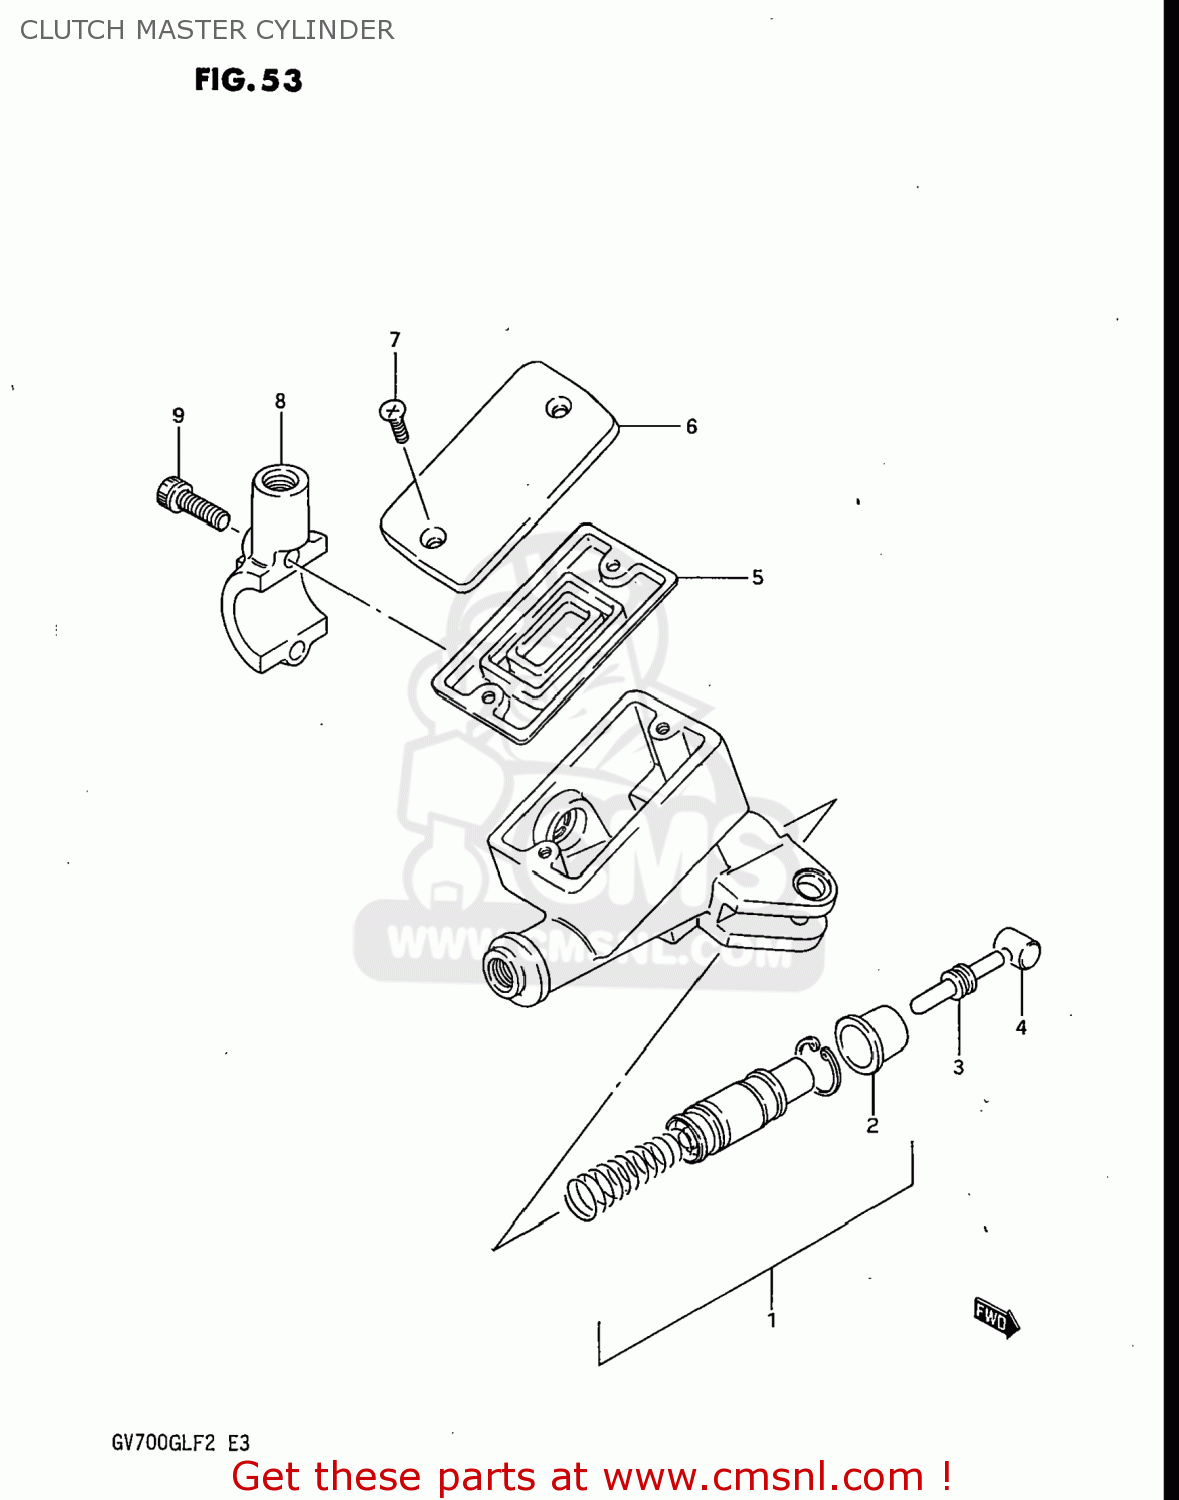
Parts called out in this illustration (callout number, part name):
1	PISTON & CUP SET
2	BOOT
3	ROD,PUSH
4	BUSH
5	6
6	CAP
7	SCREW
8	HOLDER
9	BOLT
